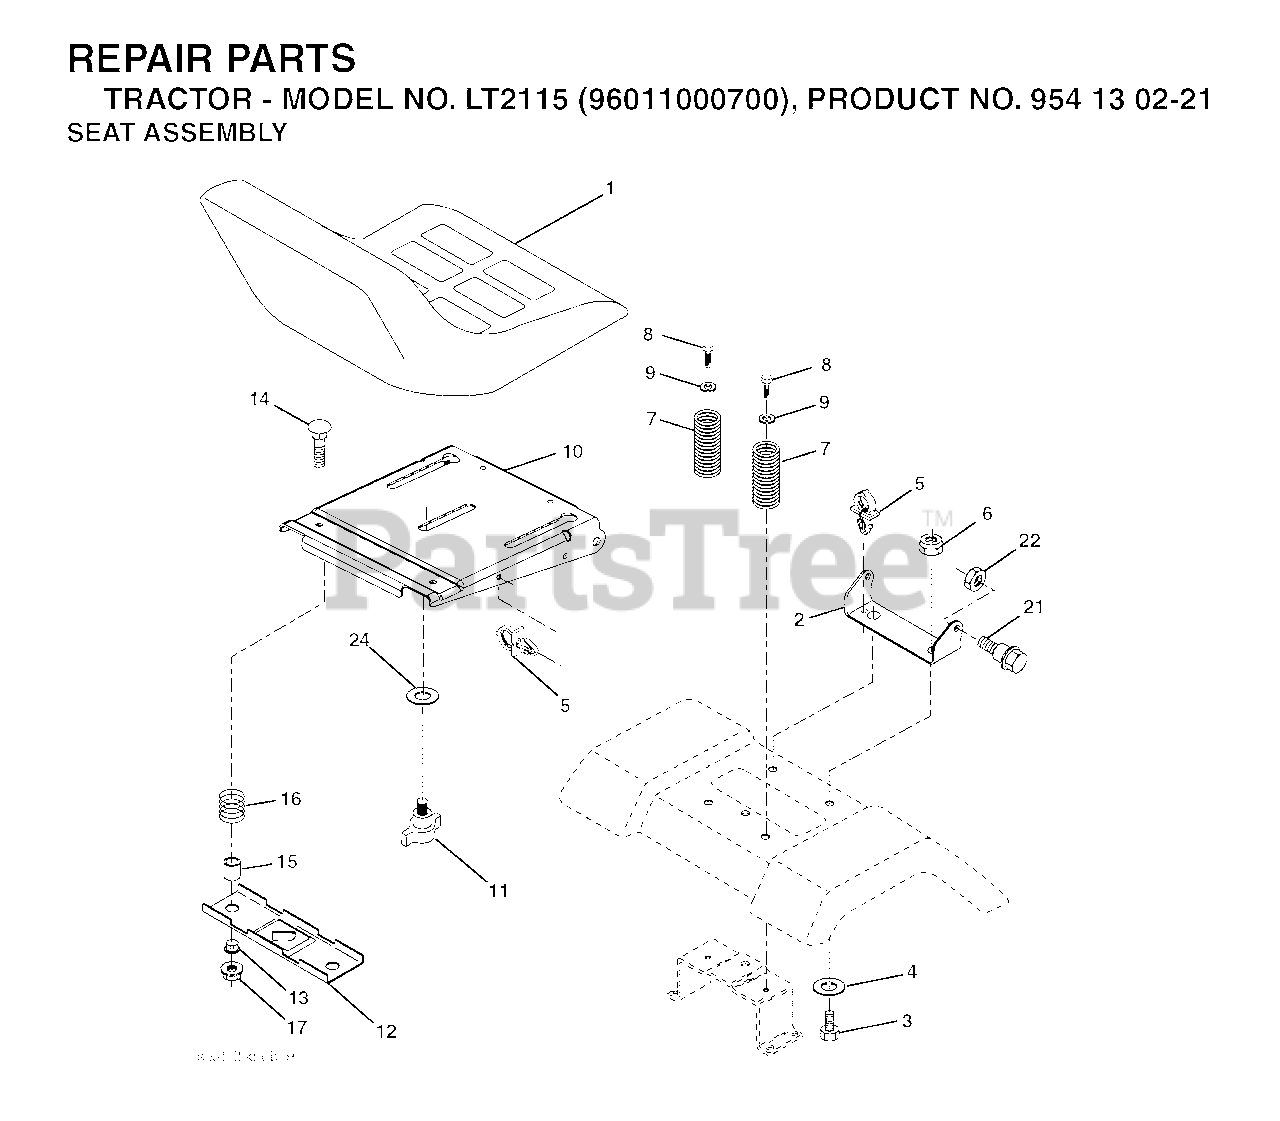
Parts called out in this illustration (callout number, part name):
2	BRKT.PIVOT.FENDER
4	WASHER PM
5	PUSH CLIP
6	NUT
7	SPRING COMPRESSION
8	SCREW 3/8-16X1
9	WASHER
11	KNOB.SEAT.ADJ.WINGNUT
12	BRKT SWITCH
14	BOLT.ROUND.HEAD.SQUARE.NECK
15	SPACER SPLIT 28X.96
17	NUT T
21	BOLT.SHOULDER.5/16-18
22	NUT.71038.31-18.HEX.NYLOCK
